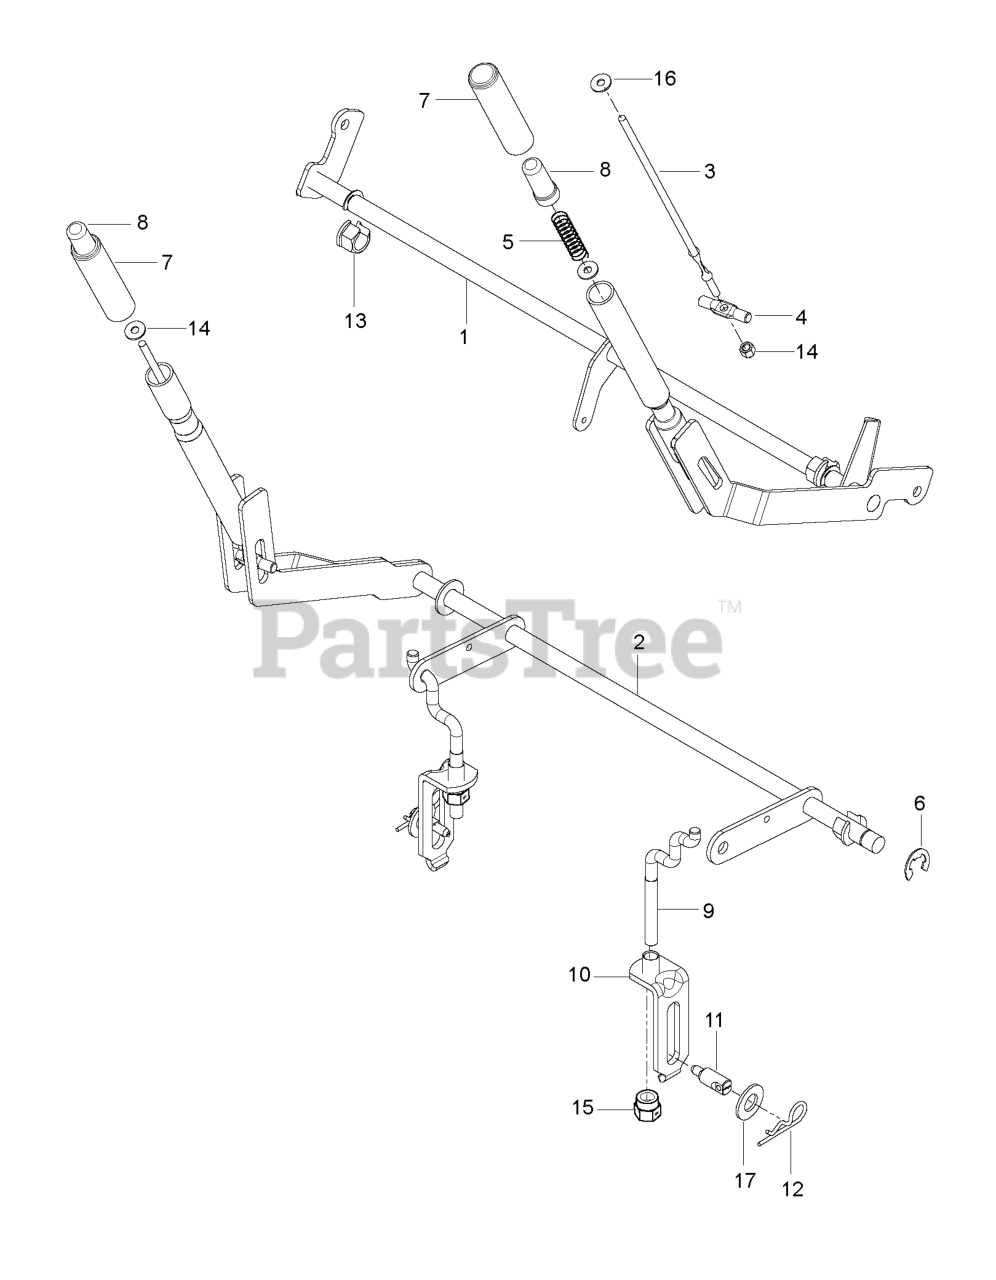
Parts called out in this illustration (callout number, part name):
1	SUB.ASM.SHAFT.BRAKE.WLDMNT.MED
2	DECK.LIFT.PNT.WELDMENT.RZ.BLK
3	ROD, HANDLE RELEASE
4	ROD LATCH RELEASE
5	SPRING, COMPRESSION
6	RETAINING RING LT
7	GRIP, HANDLE, BLACK 4"
8	BUTTON, PUSH, BLACK
9	LINK, REAR SUSPENSION
10	ASSEMBLY, BRKT LINK
11	STUD.FASTNER.W/ANTI-ROTATE
12	HAIRPIN #4
13	PLASTIC NUT
14	LOCKNUT.NYLOC.1/4-20
15	NUT, LIFT LINK 7/16-20
16	WASHER PM
17	WASHER
